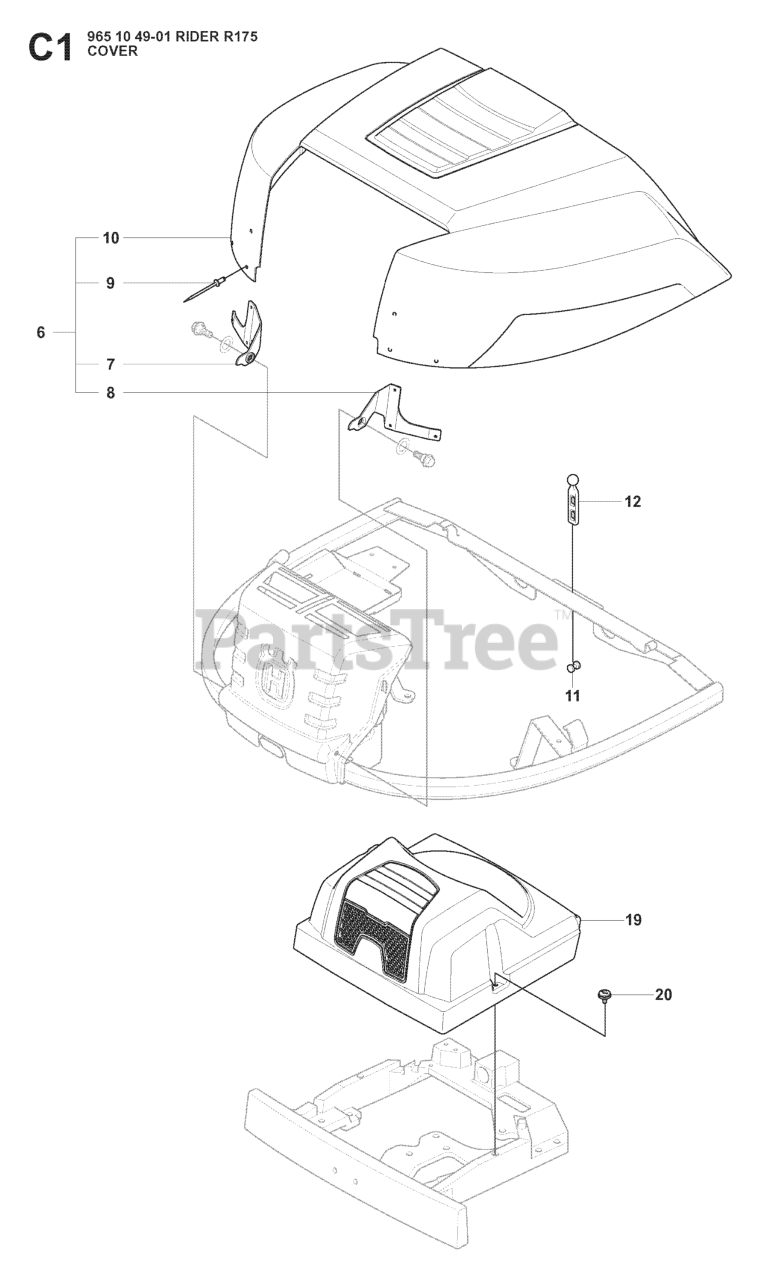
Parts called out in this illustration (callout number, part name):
6	ENGINE HOOD ASSY
10	ENGINE HOOD ASSY
12	Support Strap
19	COVER
